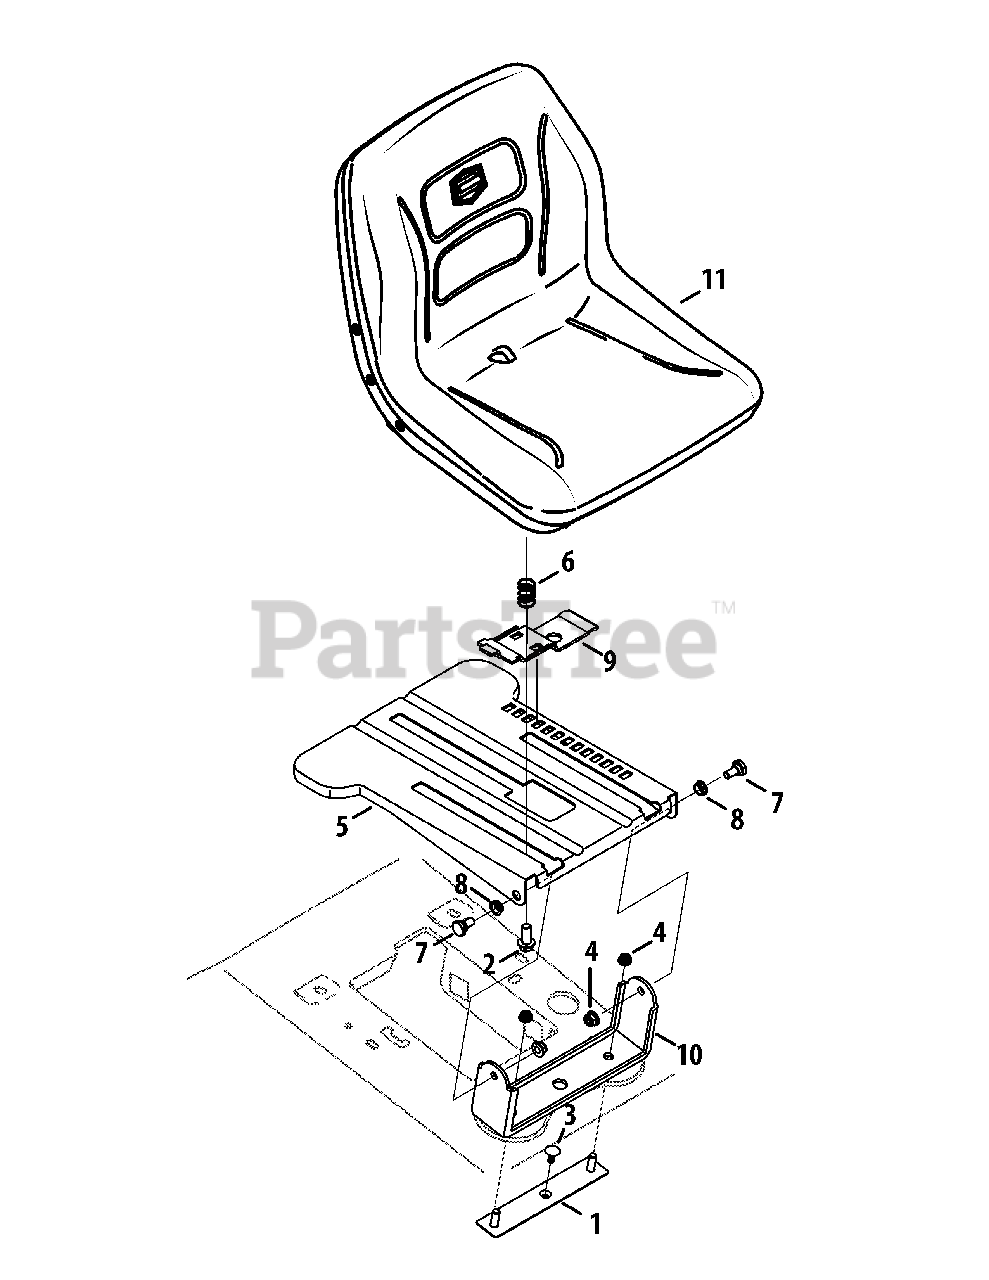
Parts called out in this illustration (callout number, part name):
1	Seat Pivot Plate Assembly
2	Hex Flange Screw, 3/8/16, .875, Gr5
3	Ratchet Clip
4	Nut, Flange Lock, 5/16-18, Grf
5	Bracket, Mounting, Seat
6	Compression Spring, .68 x 1.065 x .055
7	Shoulder Screw, .435 x .178, 5/16 x .56
8	Flange Bearing, .4385 ID
9	Seat Lever
10	Pivot Bracket, Tall
11	Seat
